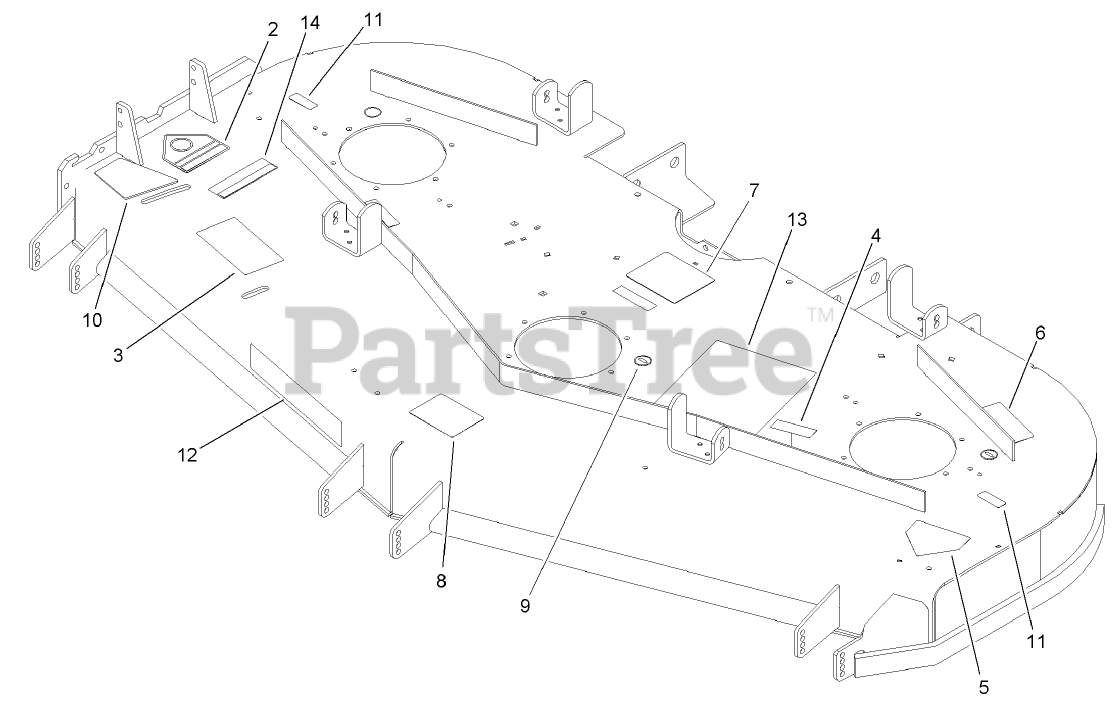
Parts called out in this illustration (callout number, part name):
2	DECAL-DANGER
3	DECAL-DANGER, THROWN OBJECT
4	DECAL-COVER, MISSING
5	DECAL-DANGER
6	DECAL-TORQUE
7	Decal-Routing, Belt
8	DECAL-SCALP, ANTI
9	DECAL-GREASE
10	DECAL-ADJUSTMENT, BAFFLE
11	Decal-Grease
13	Decal-Service, Check
14	DECAL-WARNING
